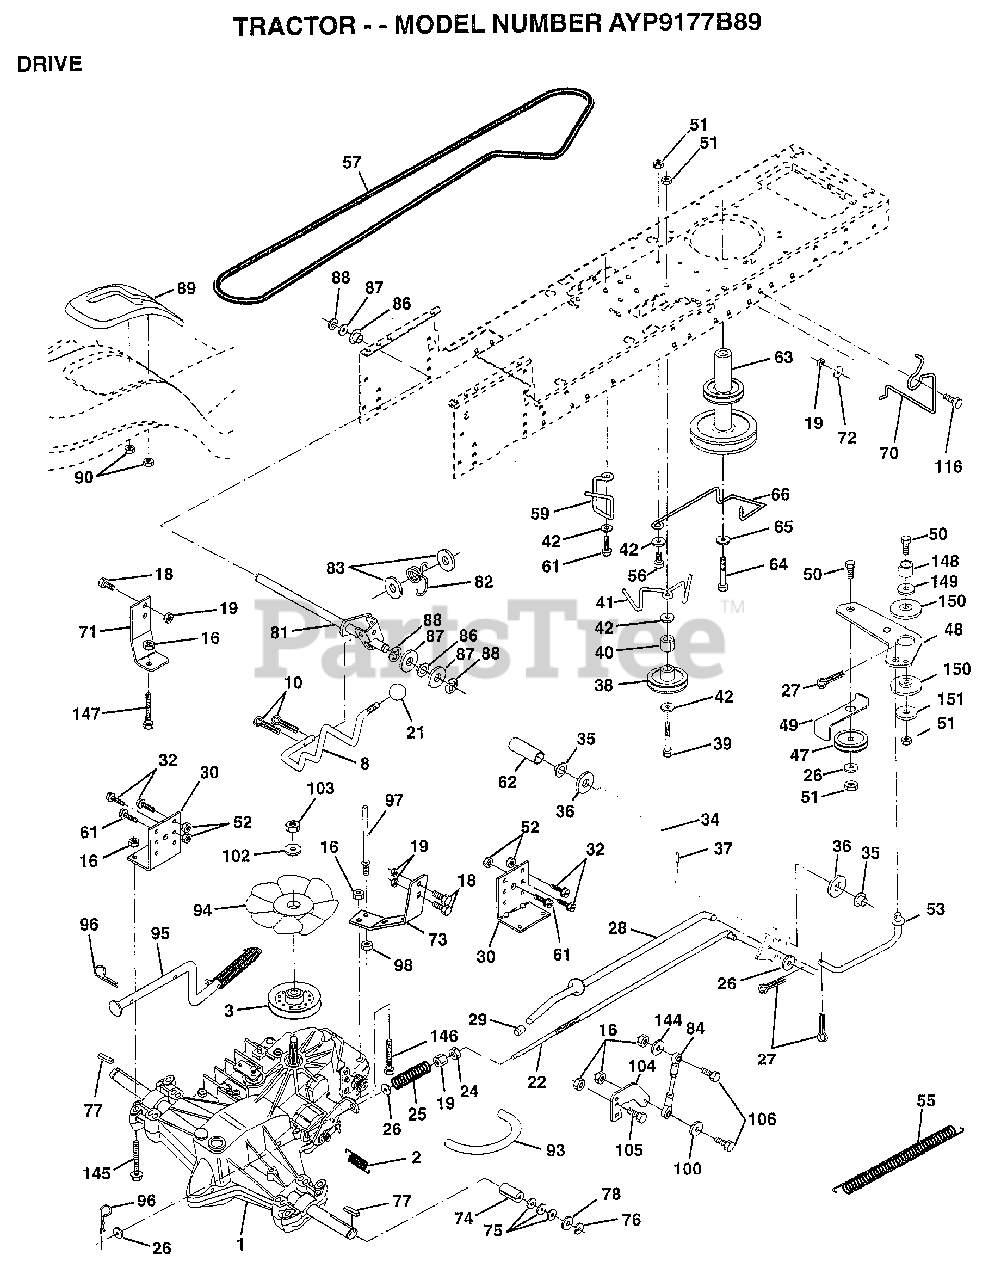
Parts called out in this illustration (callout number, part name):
1	TRANSAXLE.3100650
2	SPRING RET BRAKE
3	PULLEY.TRANSAXLE
8	"ROD SHIFT,FENDER"
10	PIN COTTER 1/8
16	NUT
18	BOLT
19	NUT
21	KNOB T (1/2-HOLE)
22	ROD.BRAKE.HYDRO.
24	NUT
25	SPRING ROD LT
26	WASHER
27	COTTER PIN
28	ROD.BRAKE.PARK.LT
30	TRANSAXLE MTG BKT
32	BOLT
34	SHAFT ASM-PEDAL F
35	NYLON BEARING
36	WASHER LT
38	PULLEY.IDLER.FLAT
39	BOLT
40	SPACER T
42	WASHER
48	BELLCRANK.CLUTCH
49	RETAIN BELT
53	"LINK, CLUTCH T"
55	"SPRING, RETURN LT"
57	"BELT.GD DRV 82"""
59	KEEPER BELT CNTSP
61	SCREW
62	PEDAL COVER T
63	PULLEY.ENGINE
64	BOLT
65	LOCKWASHER
66	KEEPER-BELT
70	KEEPER BELT ENG
71	STRAP TORQ LH HYD
72	WASHER
73	"STRAP-TORQUE,RH"
74	SPACER SPLIT
76	E-RING LT
77	SQUARE KEY
78	WASHER
81	SHAFT.CROS.20.HYD
82	"SPRING,TORSION"
83	WASHER
84	ROD.TIE
86	BUSHING
87	WASHER D
88	KLIP RING
90	NUT
93	"LINE FUEL HYD 4"""
94	"FAN 7"" HYDRO"
97	BOLT KEEPER RH
98	NUT
100	WASHER M
102	WASHER BELLEVILLE
104	ARM CONTROL HYDRO
105	SCREW CAP 5/16-18
106	BOLT
116	BOLT RDHD 3/8-16
144	WASHER
145	BOLT.HEX.FLGHD
146	BOLT.HEX.FLGHD.
147	BOLT.HEX.FLGHD
149	SPACER RETAINER
150	BUSHING.NYLON
151	WASHER
